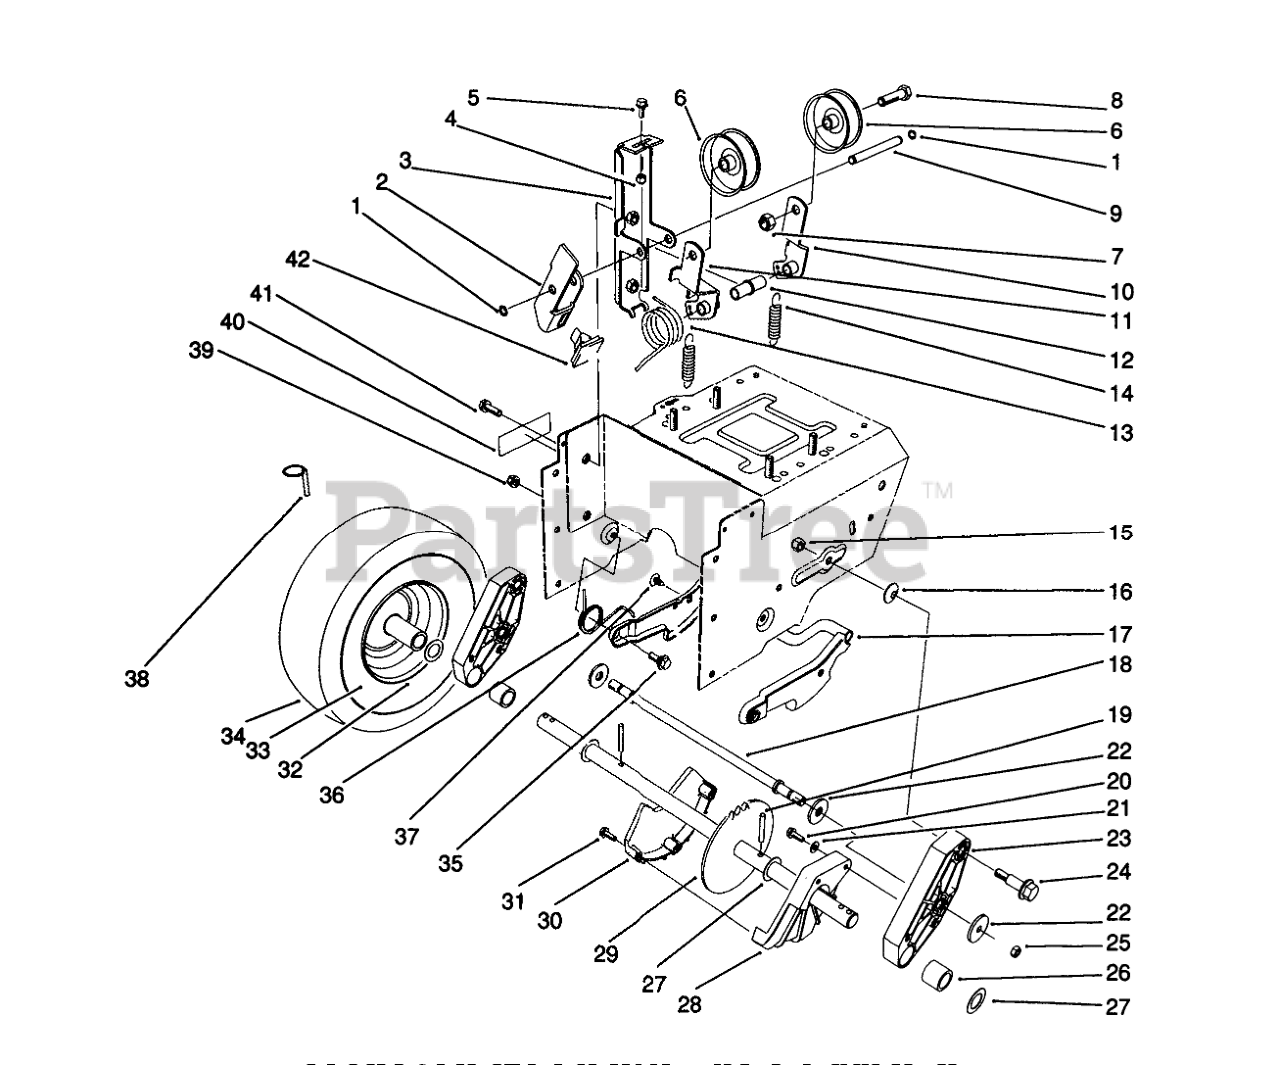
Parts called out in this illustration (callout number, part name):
1	RING-RETAINING
2	ARM-BRAKE
3	IDLER ARM BRACKET ASM
4	NUT-LOCK, NI
5	SCREW-HHF
6	PULLEY-IDLER
7	NUT-LOCK, NI
8	SCREW-HH
9	PIN-IDLER
10	ARM-IDLER, TRACTION
11	ARM-IDLER, IMPELLER
12	BUSHING-IDLER
13	SPRING-TORSION
14	SPRING-EXTENSION
15	NUT-LOCK, NI
16	WASHER-SPRING
17	Latch-Arm
18	ROD-LATCH
19	PIN-ROLL, SLOTTED
20	SCREW-HWH
21	WASHER-FLAT
22	WASHER-SUPPORT
23	Pivot Arm Assembly (Incl. Ref. #26)
24	BOLT-SHOULDER
25	NUT-LOCK, NI
26	BUSHING-AXLE
27	WASHER-THRUST
28	GUARD-CHAIN, LH
29	AXLE ASM
30	GUARD-CHAIN, RH
31	Screw
32	WHEEL
33	TUBE-INNER
35	SCREW-SHOULDER
36	SPRING-LATCH, TORSION
37	FASTENER-PANEL
38	PIN-LYNCH
39	NUT-LOCK, NI
40	DECAL-WARNING
41	SCREW-HHF
42	PAD-BRAKE
